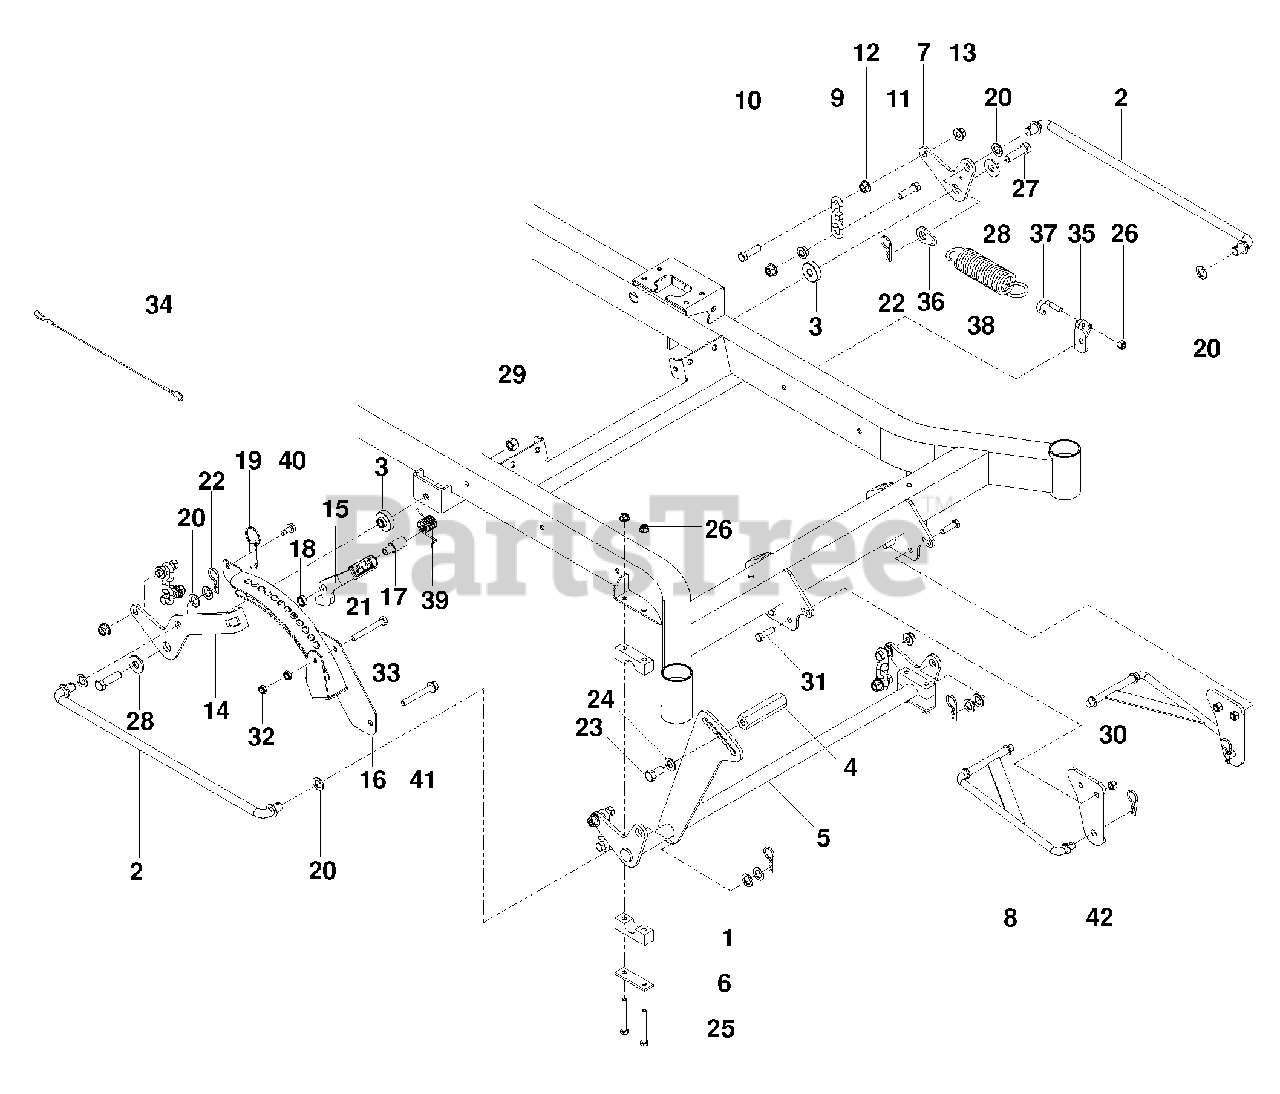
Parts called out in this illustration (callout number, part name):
1	PILLOW BLOCK
2	DECK LIFT LINK
3	SPACER, IDLER
4	PEDAL, FOOT, HEX
5	SHAFT, FRONT-LIFT
6	REINFORCEMENT BAR
7	BELLCRANK, RR, LIFT
8	STRUT LINKAGE
9	LIFT CHAIN-3 LINK
10	BOLT, HEX 7/16-14 x 1 1/2
11	BOLT, HEX 7/16-14 x 1 3/4
12	NUT 7/16-14 HEX WHIZ LK
13	NUT 7/16-14 HEX WHIZ LK
14	BELLCRANK, RR, RT
15	LATCH, TRANSPORT
16	HEIGHT, ADJUST, DECK
17	PIVOT, LATCH, TRANSPORT
18	SPACER
19	PIN 1/2 x 1 1/2 DETENT RING
20	BUSHING .625
22	PIN, COTTER 1 3/4
23	BOLT, HEX 1/2-13 x 1 3/4
24	WASHER 7/16" SPRING
25	BOLT, HEX 5/16-18 x 2 3/4
26	NUT 5/16-18 FLANGE NYLOC
27	BOLT, HEX 1/2-13 x 1 3/4 GR 8
28	WASHER 1/2 FLAT
29	NUT 1/2 HEX NYLOC
30	NUT 3/8-16 HEX NYLOC
31	BOLT, HEX 5/16-18 x 1 THD FM
32	NUT 3/8-16 HEX JAM NYLOC
33	BOLT, HEX 3/8-16 x 3
35	MOUNT, SPRING
36	TAB, SPRING
37	J-BOLT
39	SPRING, TORSION
40	BOLT 5/16-18 x 3/4 THD FRM
41	SCREW, HX FLG 3/8-16 x 2 3/4
42	MOUNT, STRUT
